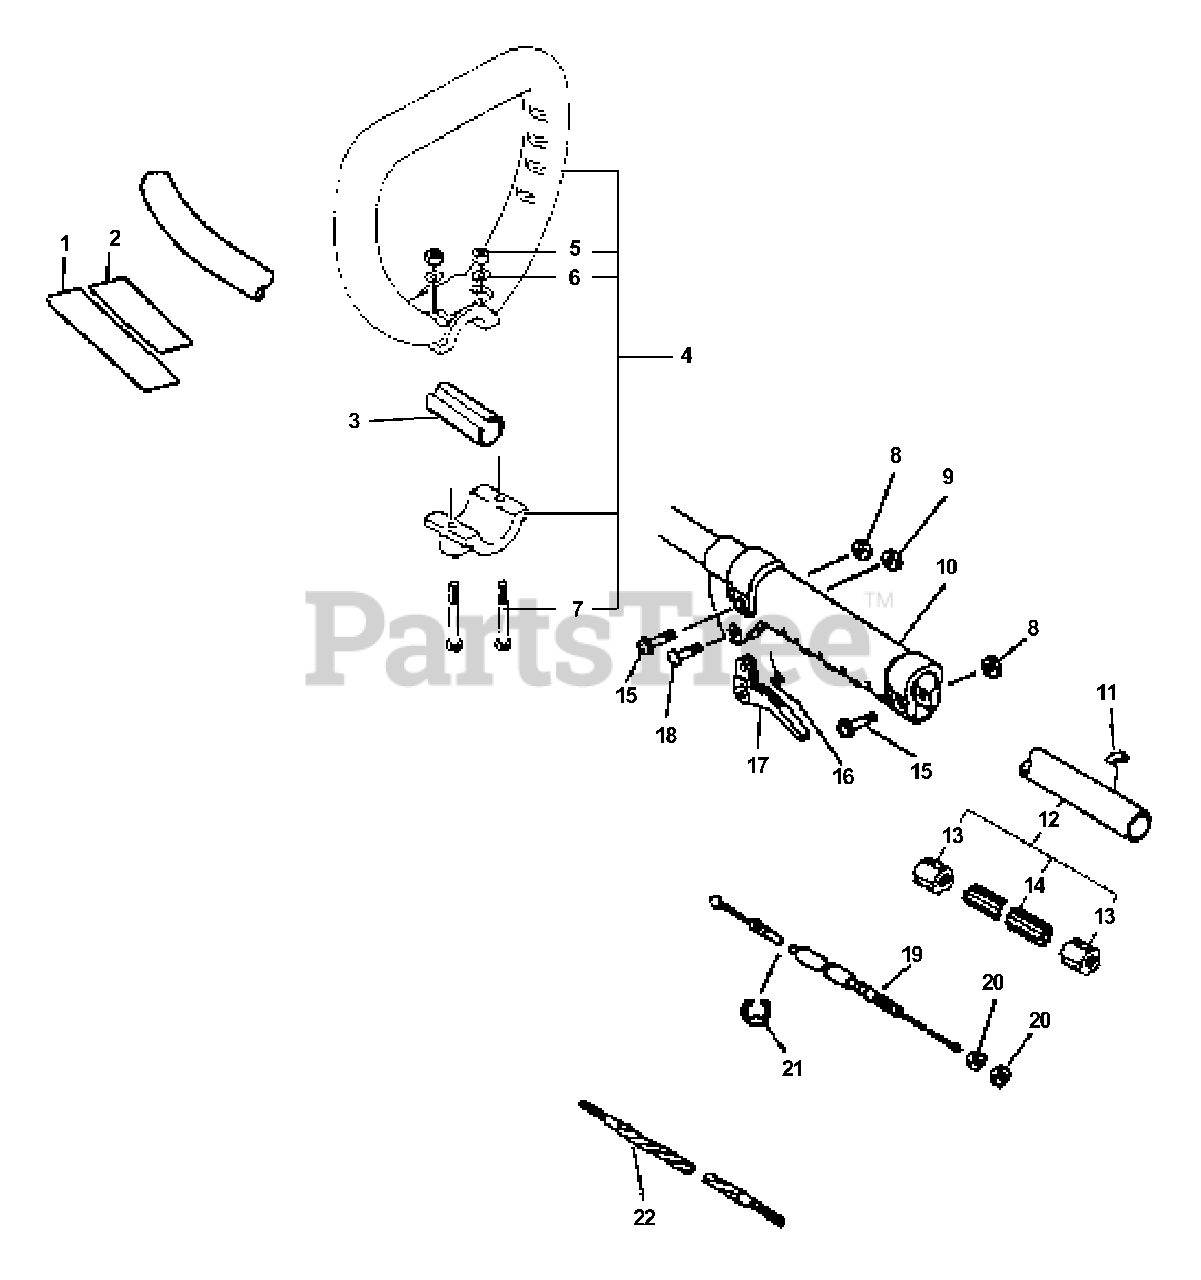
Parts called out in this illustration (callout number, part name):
1	LABEL - CAUTION
2	LABEL - CAUTION
4	LOOP HANDLE ASSY
6	WASHER - 5
7	SCREW - 5X40
9	LOCKNUT - 5
10	GRIP, HANDLE
11	LABEL - ALIGNMENT
12	MAIN PIPE ASSY
14	LINER - FLEXIBLE
15	SCREW - 5X25
16	SPRING, TRIGGER
17	TRIGGER, THROTTLE
18	SCREW - 5X30
19	CABLE, THROTTLE
21	RING, RETAINING - 5
22	DRIVESHAFT - FLEXIBLE
